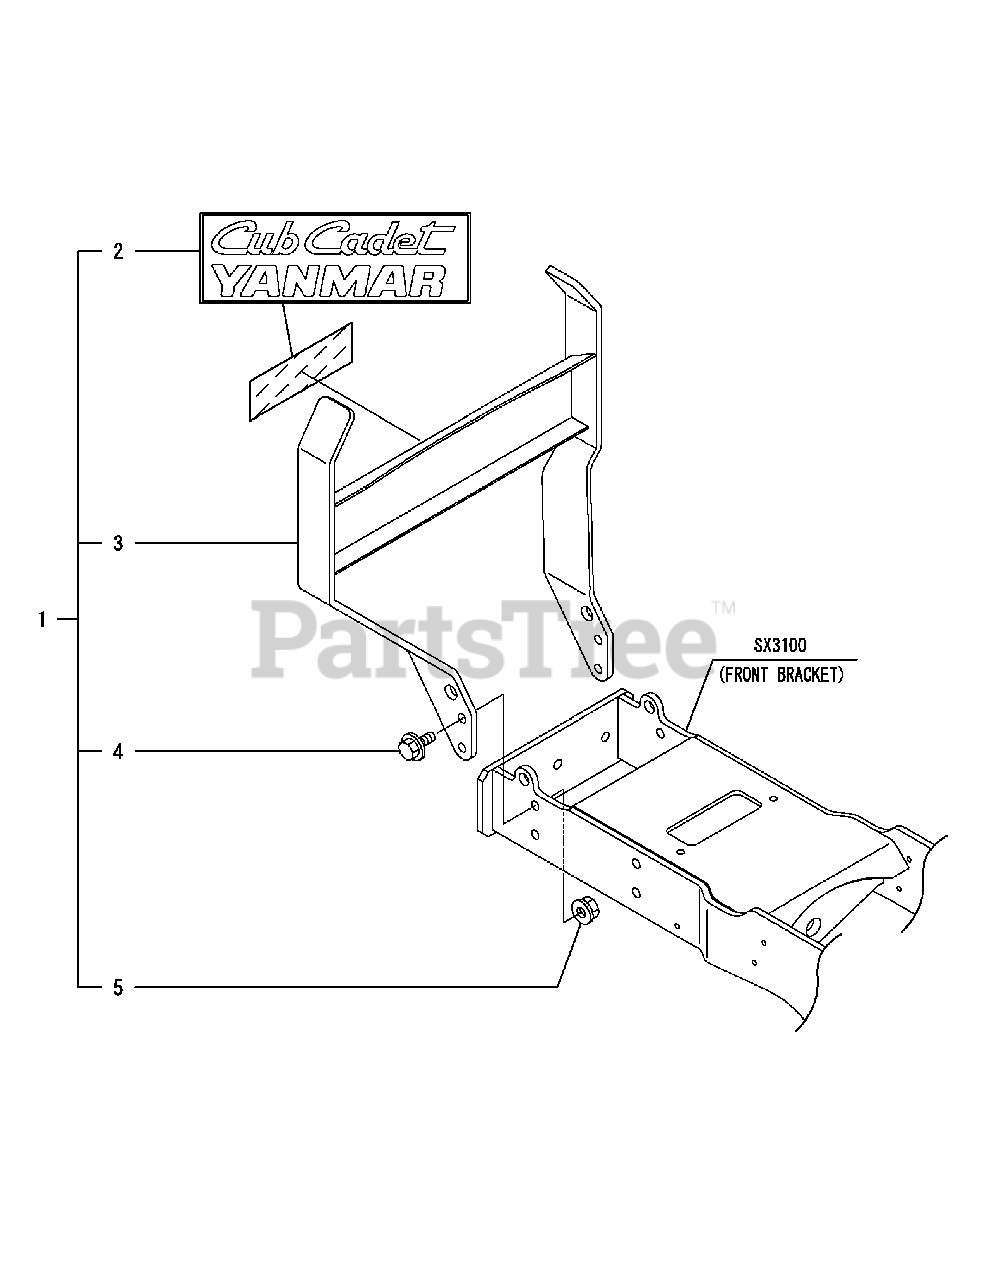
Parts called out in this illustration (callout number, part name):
1	Grille Guard Kit
2	Label, Grill Guard
3	Grille Guard Cmp
